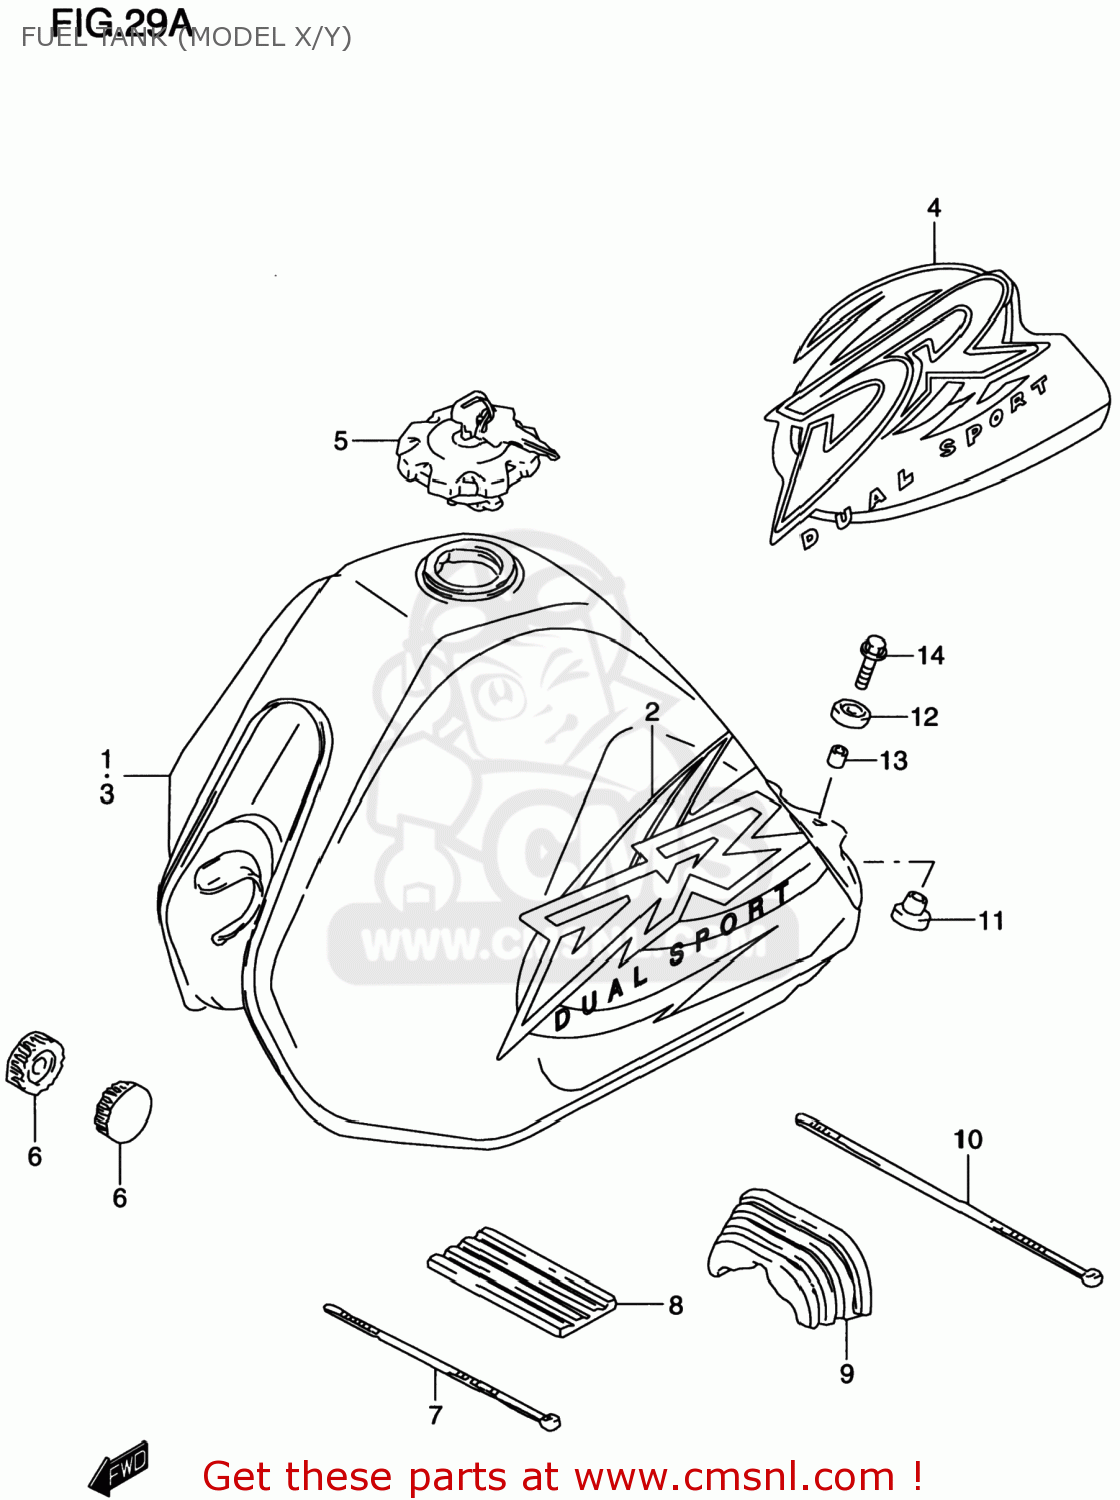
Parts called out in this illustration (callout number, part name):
1	TANK ASSEMBLY,FUEL
2	TAPE SET,FUEL TANK
3	TANK ASSEMBLY,FUEL
4	TAPE SET,FUEL TANK
5	CAP SET,FUEL TANK
6	CUSHION
7	CLAMP(L:250)
8	CUSHION,FUEL TANK UPR FR
9	CUSHION,FUEL TANK RR
10	CLAMP(L:300)
11	CUSHION
12	CUSHION
13	SPACER(6.5X9X18)
14	BOLT
